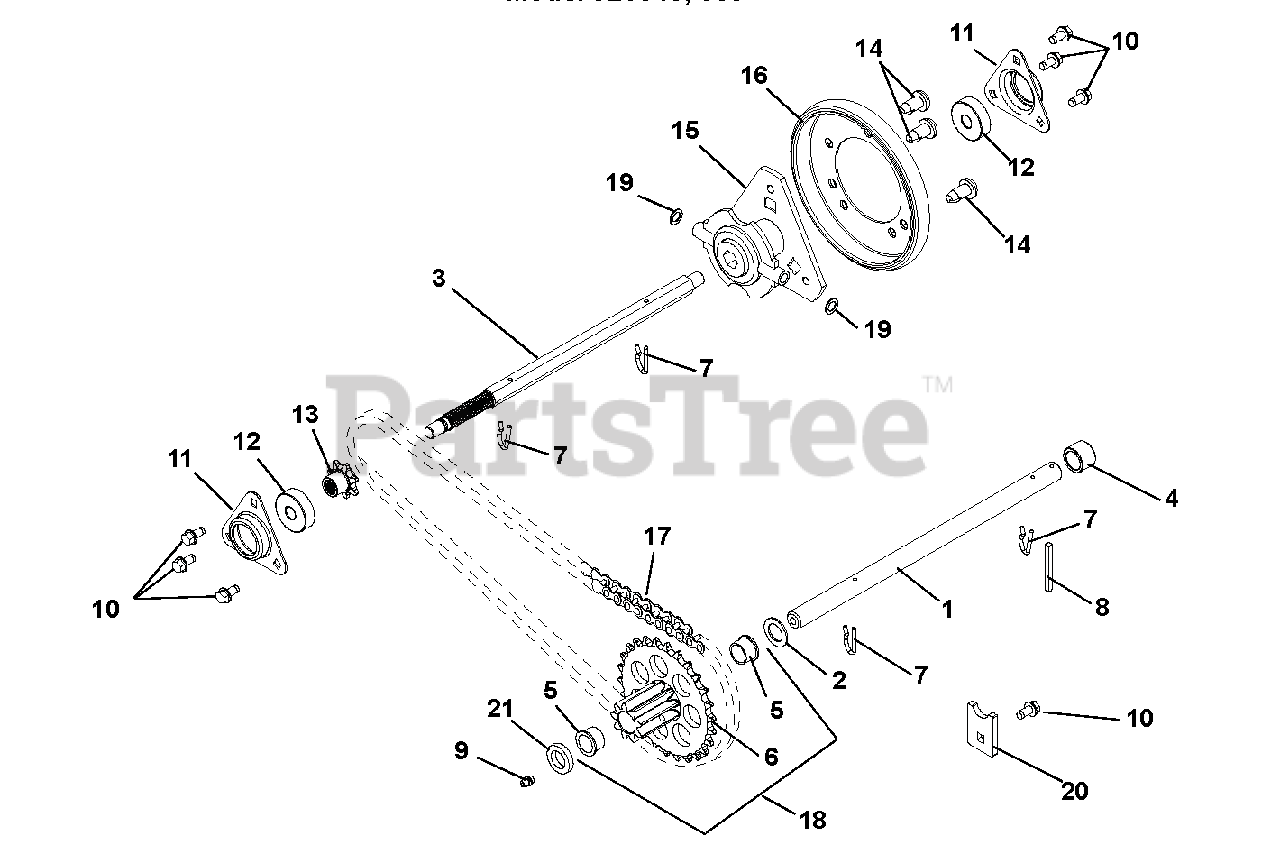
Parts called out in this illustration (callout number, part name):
1	SHAFT, PINION - HARDENED
2	WSHR-FL-STL .630X1.005X.062 YZ
3	SHAFT, HEX-W/SPLINE TRACK
4	SPACER, .635X.880X.611
5	BSHG-FLG .625X.750X.500X.875
6	PINION & SPROCKET
7	PIN, SPRING CLIP
8	@PIN-GRV .125X1.00 TP E ALLOY
9	ZERK,FITTING .25X.125 DRIVE IN
10	SCR-TAP .25-20X.50 HWH TR YWZ
11	FLANGE, BEARING
12	BRG-BALL .437X1.375X.437
13	SPROCKET, PINION 7T W/SPLINE
14	SCR-TAP SERRDHDTX .31-18X.50BP
15	CARRIER, DRIVE DISK
16	FRICTION, DISC
17	CHAIN - #41, 32 PITCHES
18	PINION & SPROCKET W/BUSHINGS
19	WSHR-FL-STL .505X1.00X.062YWZC
20	TAB, ANTI ROTATION
21	BSHG-SLV, .635X.880X.305
